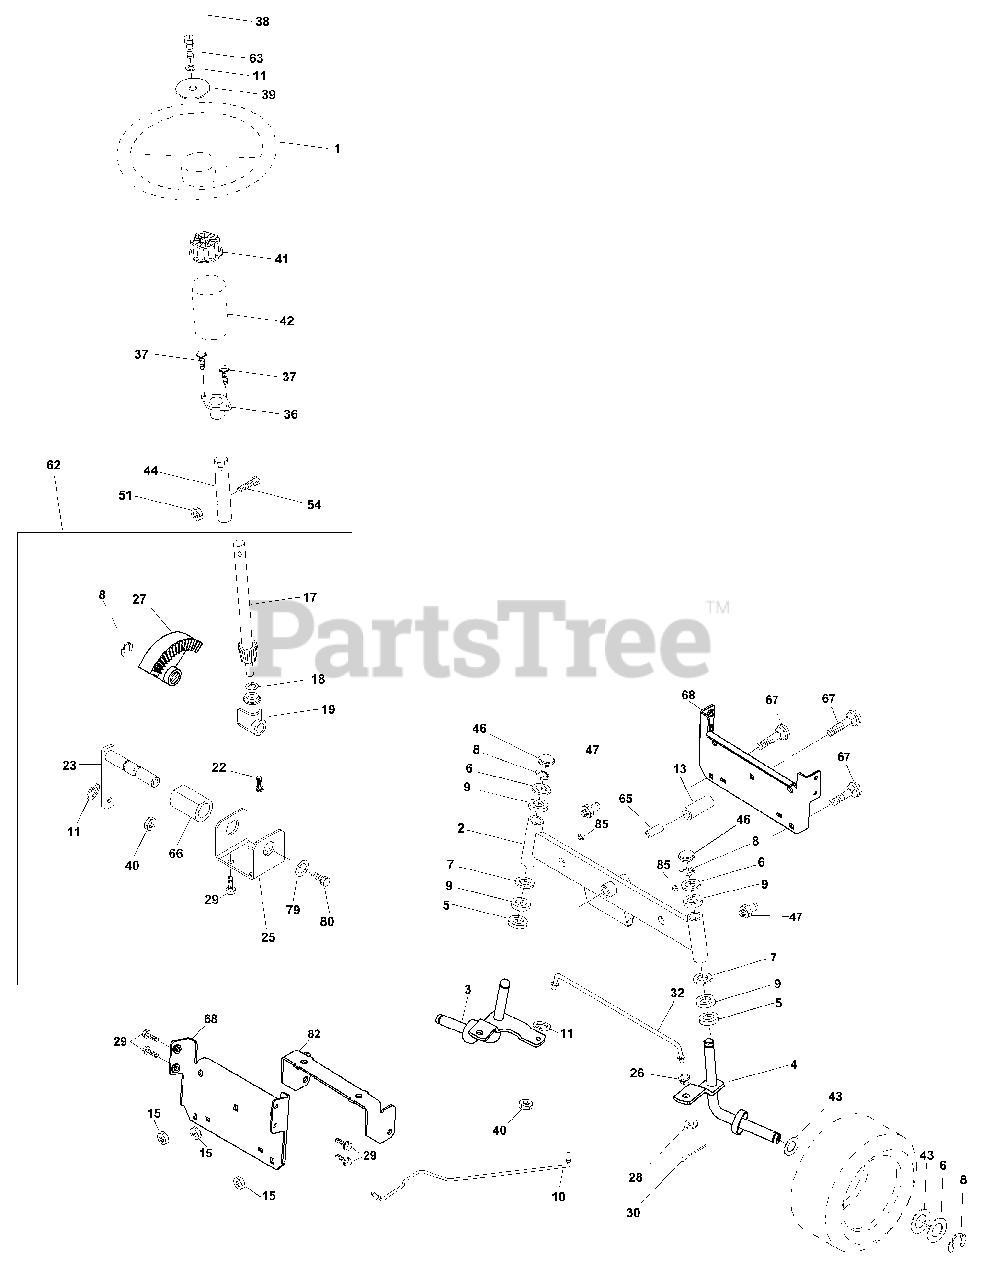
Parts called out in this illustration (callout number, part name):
1	Wheel Steering Ayp/P/L Blk
2	Axle Asm
3	Spindle Asm LH
4	Spindle Asm RH
5	Bearing Race Thrust Harden
6	Washer 25/32 X 1-5/8 X 16 Ga
7	Washer 27/32 X 1-1/4 X 16 Ga
8	Ring Klip #t5304-75
9	Bearing Col Strg Blk
10	Link Drag
11	Washer Lock Hvy Hlcl Spr 3/8
13	Spacer earing Axle Front
15	Hexflange Lock
17	Shaft Asm Strg
18	Washer Thrust 515 x 750 x 033
19	Support Shaft
22	Screw Hex Wsh Hd Torx
23	Shaft Asm Pittman
25	Bracket Steering
26	Bushing Link Drag Blk LR
27	Gear Sector
28	Washer 13/32 X 7/8 X 16 Ga
29	Screw 3/8-16 x 3/4
30	Pin Cotter 1/8 X 3/4 Cad
32	Rod Tie Wire Form 19 75 Mech
36	Bushing Strg 5/8 Id Dash
37	Screw
38	Cap Wheel Steer Ayp
40	Nut Lock Center 3/8-24un
41	Adaptor Wheel Strg
42	Boot Dash Mtl Steering Blk
43	Washer 25/32 X 1 1/4 X 16 Ga
44	Extension Steering
46	Cap Spindle Fr Top Blk
47	Fitting Grease
51	Nut Lock Hex W/Ins 5/16-18
54	Bolt Fin Hex 3/8-16unc x 1-1/4
62	Kit Steering Assembly Service
63	Bolt Fin Hex 3/8-16unc x 1 Gr.5
65	Spacer Brace Axle
66	Bearing Arm Pittman
67	Bolt Fin Hex 5/8-11 unc x 2-3/4
68	Brace Axle
79	Washer 13/32 x 1 1/4 x 12 Ga.
80	Bolt Hex 3/8-16 x 3/4
82	Bracket Susp Chassis Front
85	Fastener Christmas Tree
